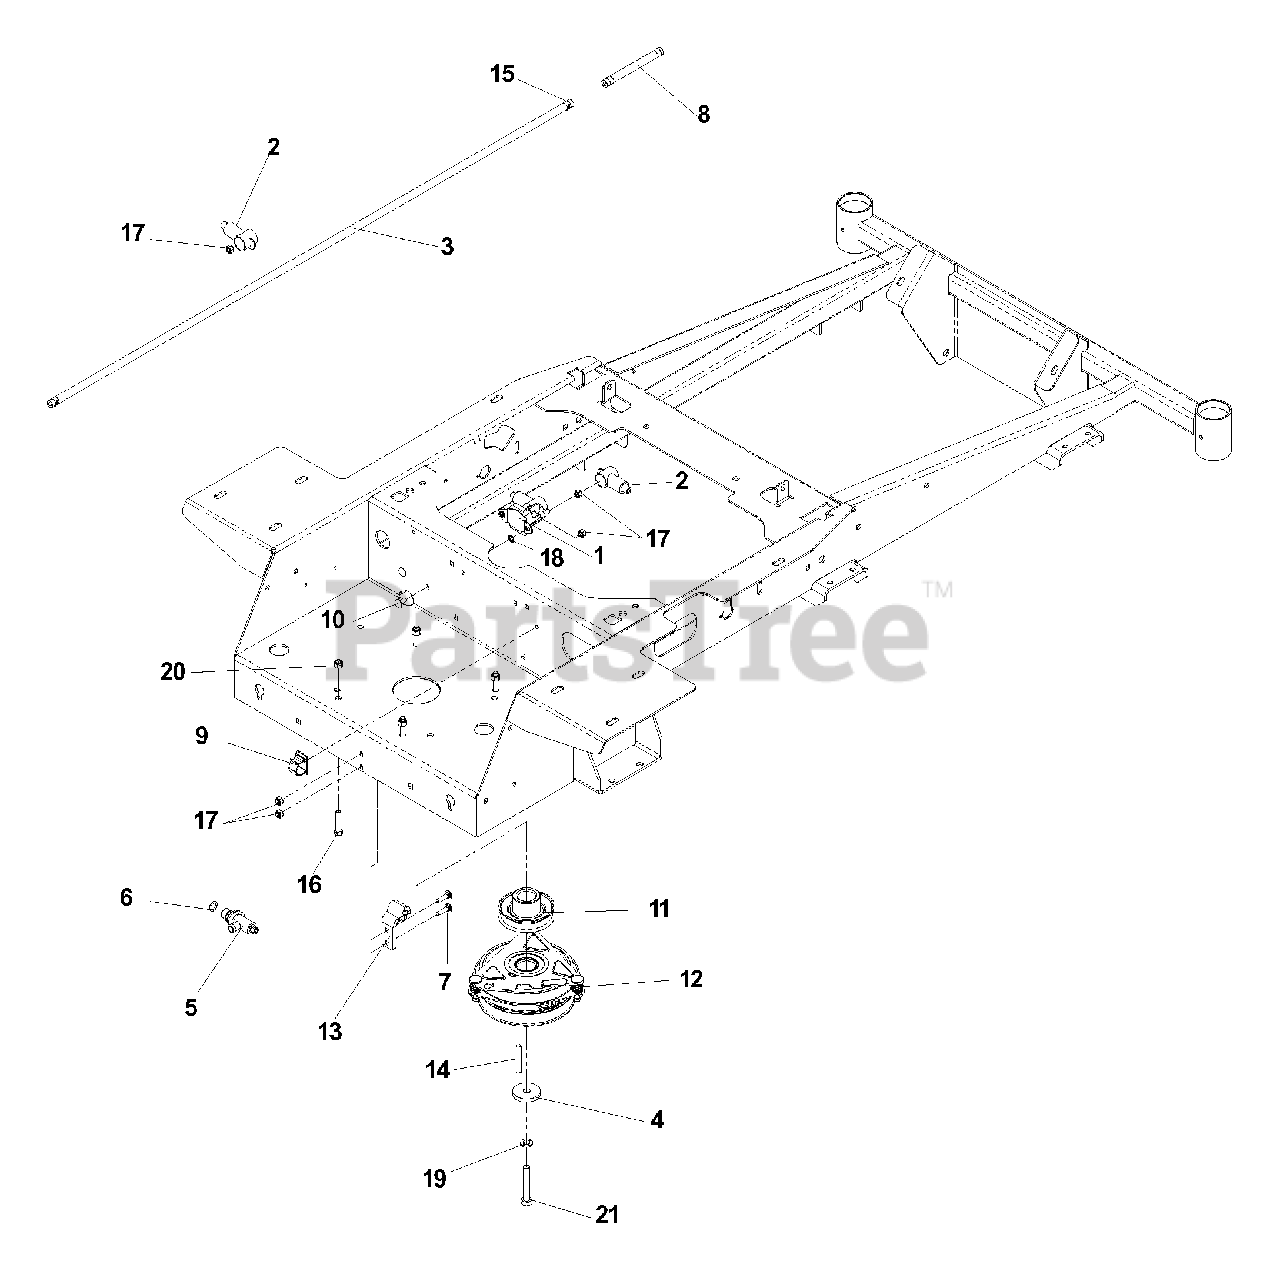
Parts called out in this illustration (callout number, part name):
2	INSULATOR, BATTERY
4	WASHER, .469
5	OIL DRAIN EXTENSION
7	RHSNB, 1/4-20 X 1, GR5
8	FUEL LINE, 5"
9	PUSH-MOUNT WIRE CLIP
10	RHSSNB, 1/4-20 X 5/8, GR5
11	PULLEY, DRIVE
13	CLUTCH TIE DOWN
14	KEY, 1/4 SQ X 2
15	CLAMP, HOSE
16	HCS, 5/16-18 X 1 1/2, GR5
17	NUT, 1/4-20, NYLOC
18	WASHER, 1/4
19	WASHER, 7/16
20	NUT, 5/16-18, NYLOC
21	HCS, 7/16-20 X 2 1/2, GR5
